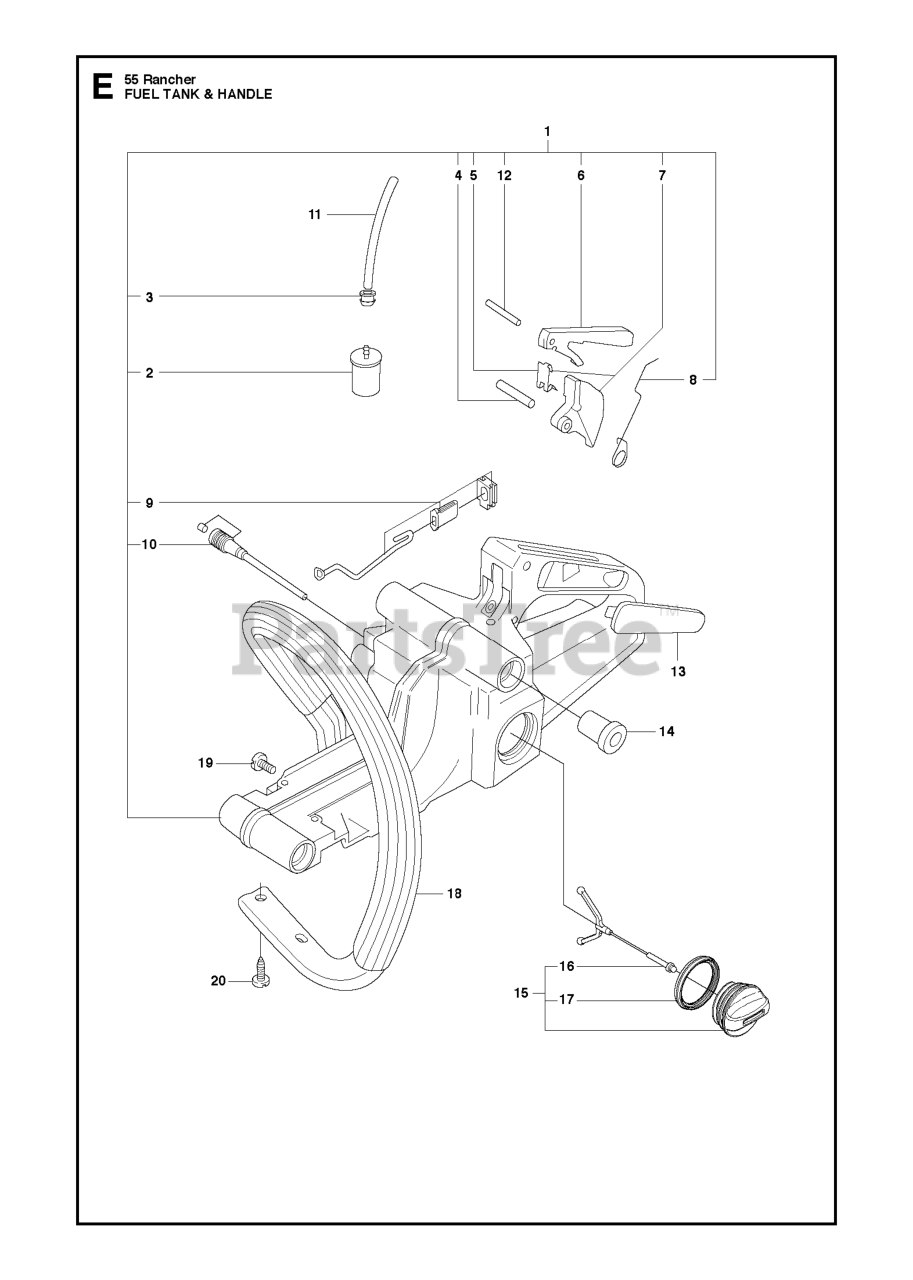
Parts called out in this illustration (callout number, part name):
2	RP FUEL FILTER
3	FUEL TANK BUSHING
5	RP PROTECTOR
6	THROTTLE CATCH
9	THROTTLE PUSH ROD CPL
10	FUEL TANK VENT
11	HOSE
13	HANDLE FILLER
14	ANTIVIBE ELEMENT
15	TANK CAP
18	FRONT HANDLE
19	SCREW
20	SCREW
